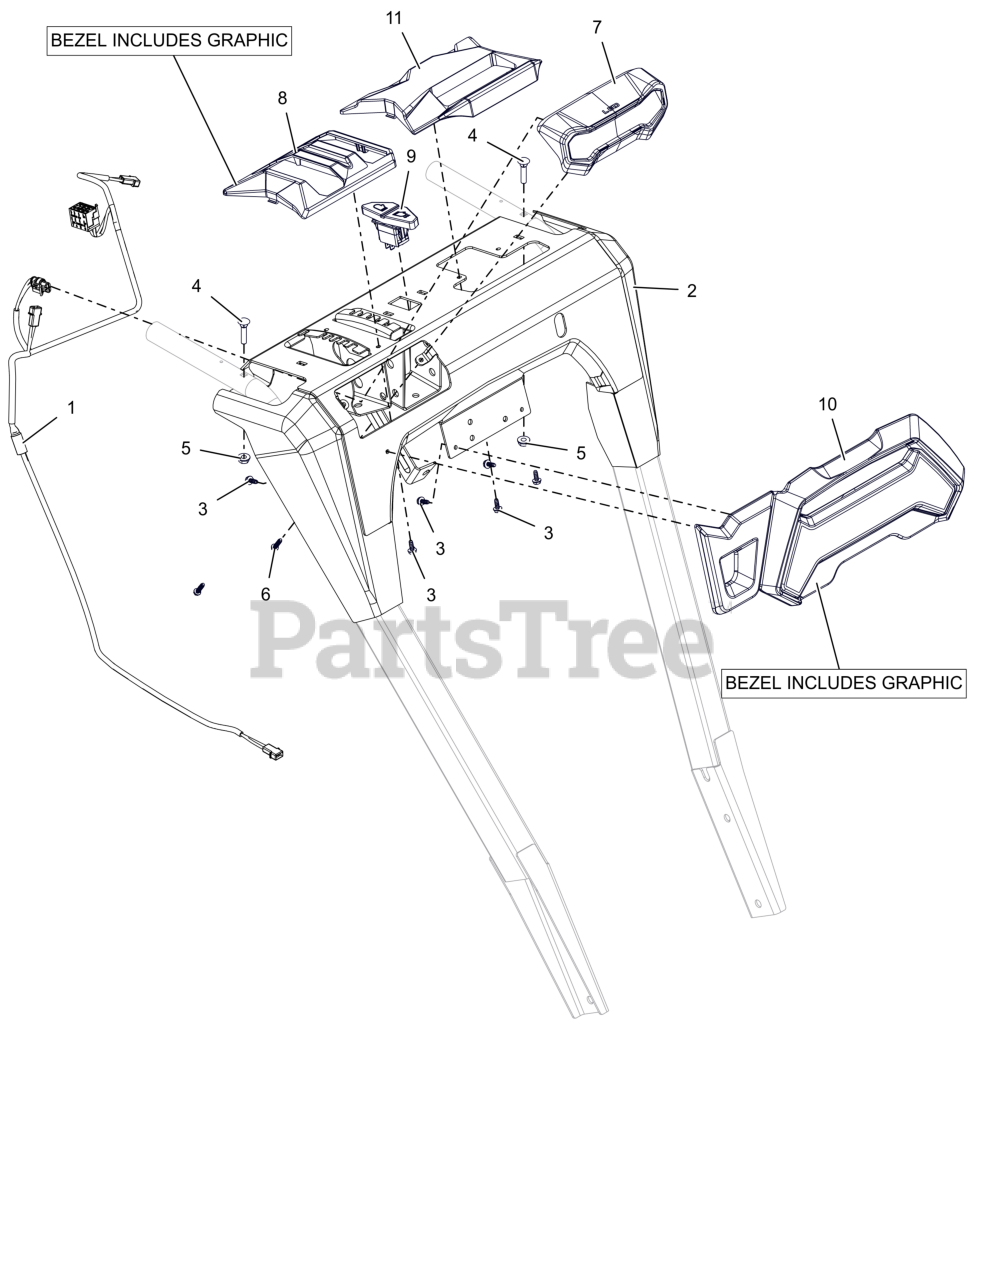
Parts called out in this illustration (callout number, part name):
1	HARNESS- WIRE - LT HG
2	PANEL, DASH-FRICTION QT W/DECAL
3	SCR, PLASTIC #10X.50
4	BLT-RDHDXLSQNK.25-20X1.25 G5ZC
5	NUT-LK-CTR-FLG .25-20 ZC120
6	SCR-HWH 10-16X.75 HI-LO ZCC
7	HEADLIGHT ASM- LED
8	BEZEL, SHIFT - FRICTION
9	SWITCH- ROCKER SPST-ON/OFF
10	BEZEL- LARGE - PROFESSIONAL
11	BEZEL, OPERATOR CHUTE DECAL
